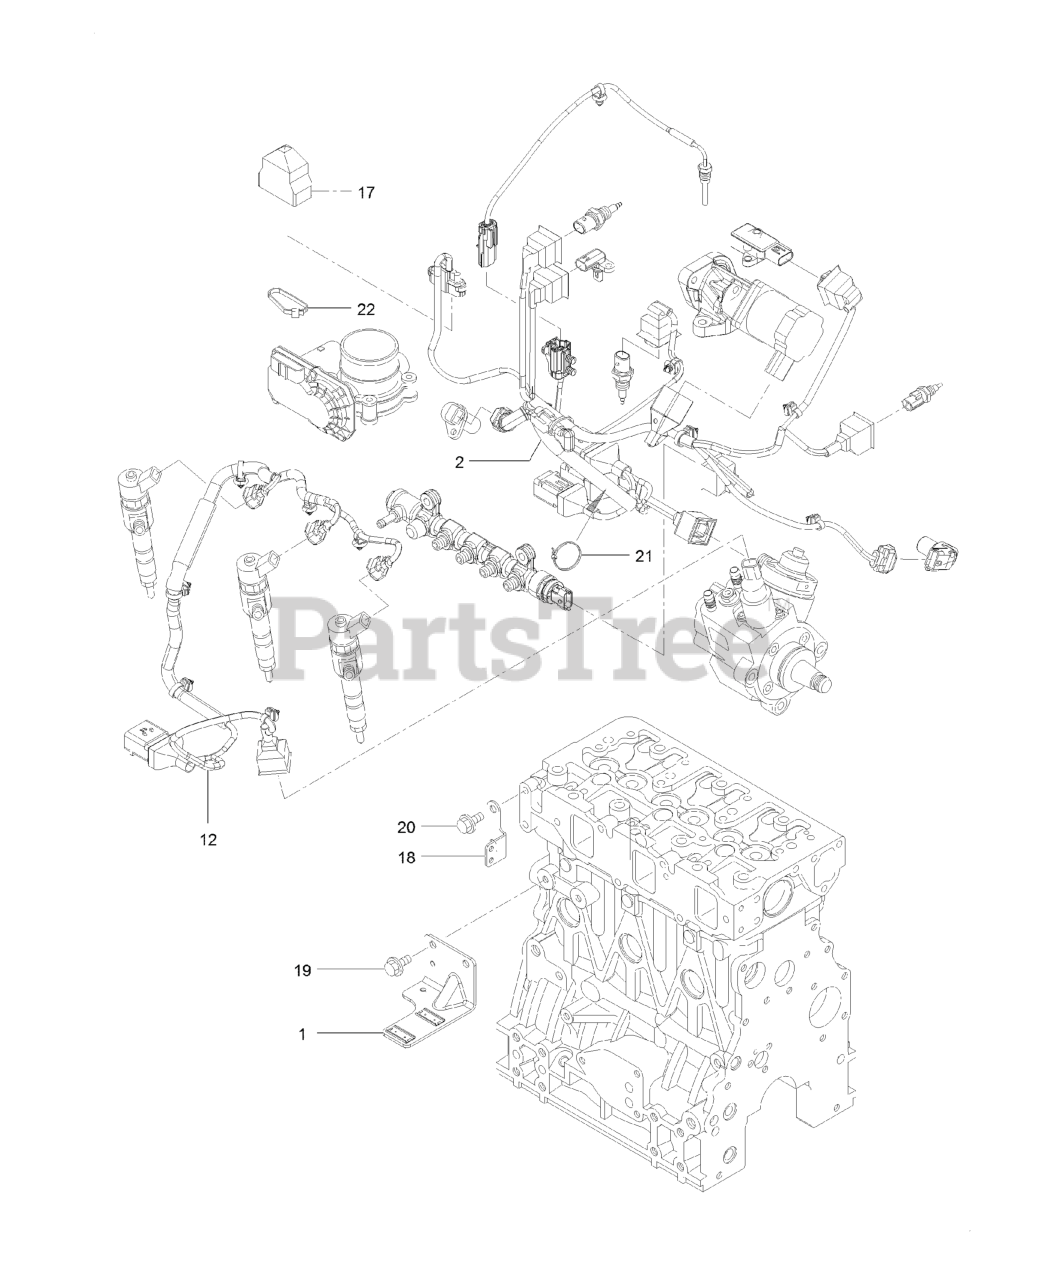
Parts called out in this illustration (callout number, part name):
1	BRACKET-CONNECTOR
2	HARNESS
12	HARNESS
17	Boot-Cap
18	Bracket-Harness
